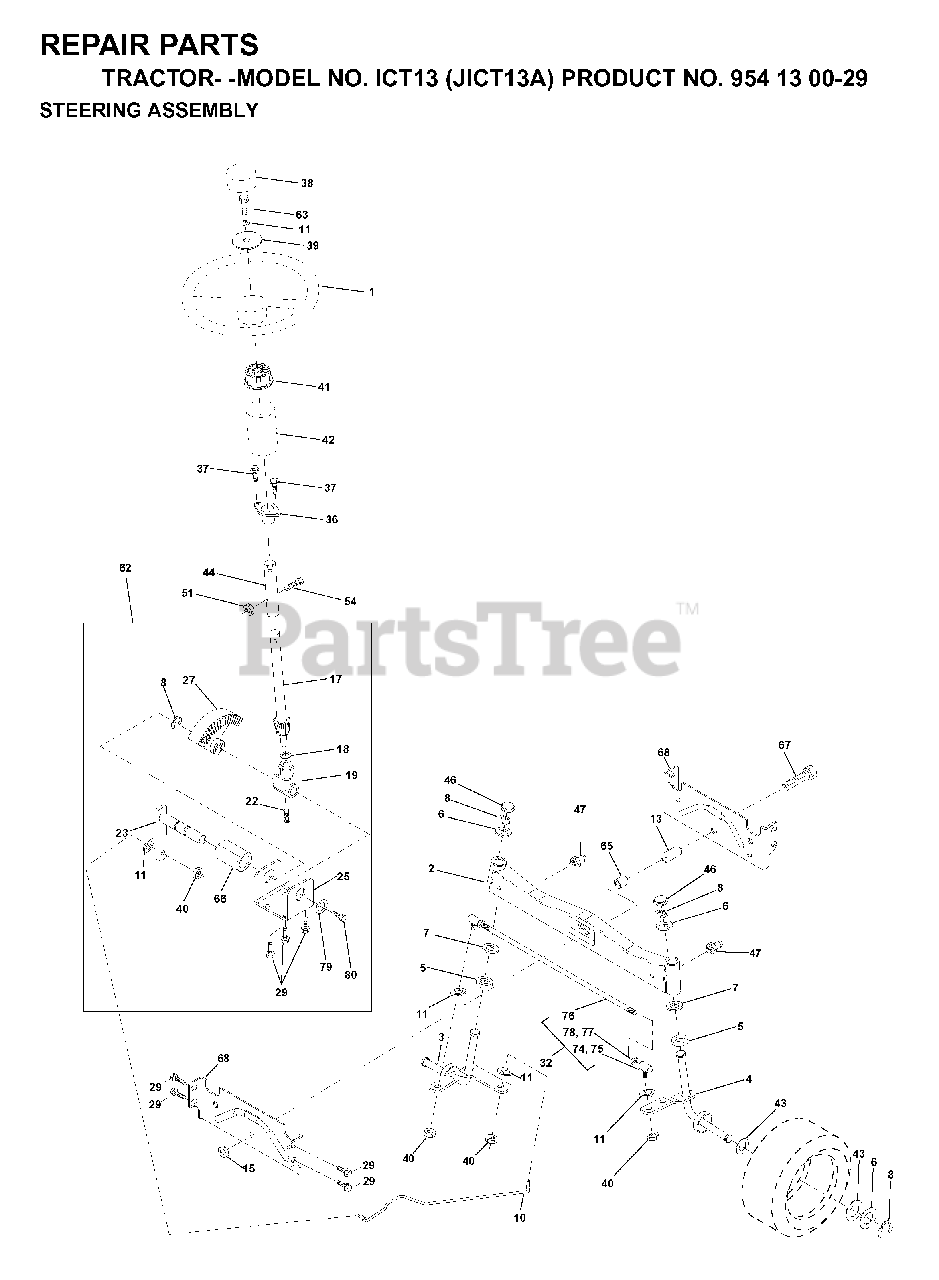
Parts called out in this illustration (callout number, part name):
2	FRONT AXLE ASSY
3	SPINDLE ASM LH
4	SPINDLE ASM RH
8	RING CLIP
10	LINK.DRAG.DROPPED.LT
11	WASHER, LOCK 3/8
13	SPACER, FRT AXLE BRNG
15	NUT-LOC,FLANGE LT
17	SHAFT ASM STEERING
18	THRUST WASHER
19	STEERING SHAFT SUPPORT
22	SCREW.HX.WSH.HD
23	SHAFT ASSY PITTMAN
25	BRACKET STEERING
27	GEAR.SECTOR
29	SCREW
32	ROD ASSY/TIE BALL
36	BUSHING, STEERING
38	RP INSERT
39	WASHER T
40	GRIPCO NUT
41	ADAPTER LT
42	STEERING BOOT, GRAY
44	EXT SHAFT STEERING
46	CAP.SPINDLE
47	ZERK M
51	NUT.71038.31-18.HEX.NYLOCK
54	BOLT.5/16-18X1-1/4 FULL.THREAD
62	STEERING KIT
65	SPACER AXLE
66	BEARING ARM
67	BOLT.HEX.FINISHED.5/8
68	AXLE, BRACE
74	JOINT
76	TIE ROD
80	BOLT.HX.NYLON3/8-16X
